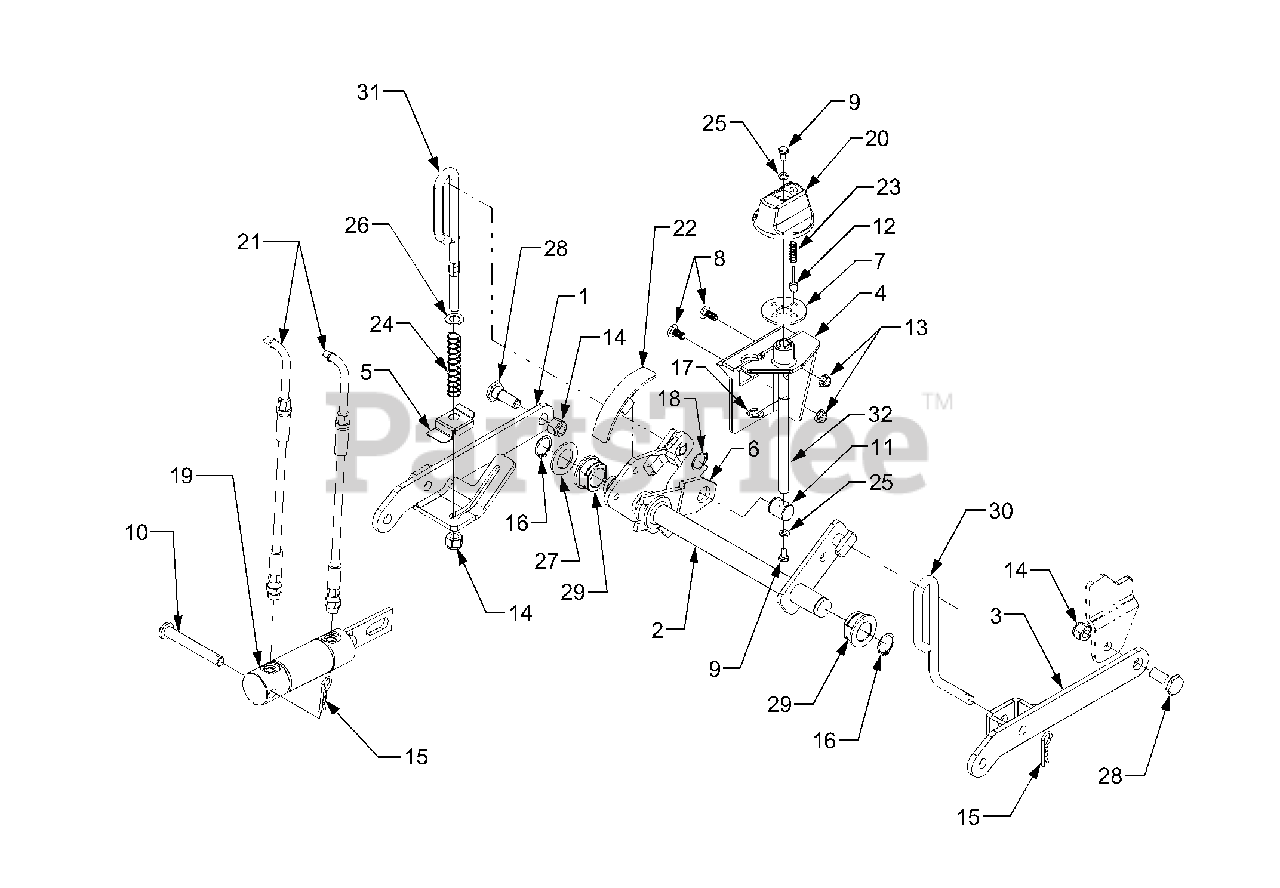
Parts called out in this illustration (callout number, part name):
1	Link, LH Lift
4	Bracket, Downstop
5	Stop Bracket, Lift Rod
6	Arm, Downstop
7	Disk, Detent
8	Bolt, Carriage, 3/8-16 x .75
9	Screw, Hex Cap, 1/4-20 x .5 GR5
10	Pin, Clevis, .5 x 3.75
11	Ferrule, Adjustment
12	Pin, Detent Plunger
13	Nut, Flange Lock, 3/8-16 GR5
14	Nut, Hex Lock, 1/2-13
15	Pin, Internal Cotter
16	Snap Ring, 1.0 Dia. Shaft
17	Ring, `E' Retaining, .5 Dia.
18	Snap Ring, .875 Dia. Shaft
19	Cylinder, Center Lift
20	Knob
21	Hose, Lift
22	Indicator, Lift Position
23	Spring, Compression
24	Spring, Compression
25	Washer, Flat, .281 x .5 x .063
26	Washer, Flat, .536 x .93 x .050
27	Washer. Flat, 1.0 x 1.7 x .10
28	Shoulder Screw
29	Bearing, Flange w/Flats
30	Rod, RH Lift
31	Rod, LH Lift
32	Screw, Adjustment
